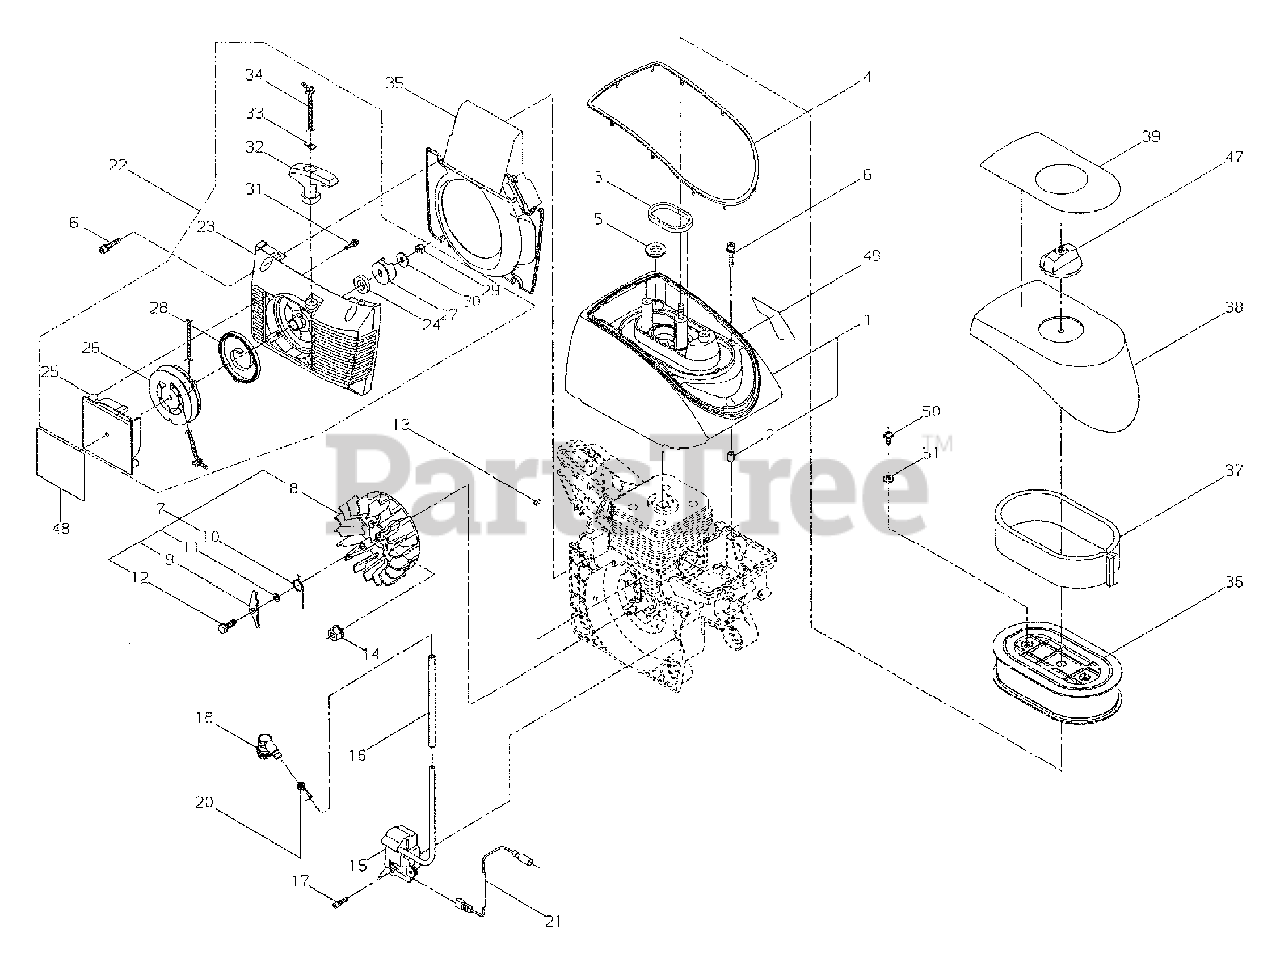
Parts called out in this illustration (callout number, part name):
1	ENGINE COVER KIT
3	SEAL
4	SEAT, SEAL
5	PLUG
6	BOLT 5
7	FLYWHEEL
8	FLYWHEEL
9	RATCHET
10	SPRING
11	COLLAR
12	BOLT
13	KEY, WOODRUFF 3×10
14	NUT M8×1.0
15	COIL
16	TUBE
17	BOLT M4×16
18	CAP, SPARK PLUG
20	TERMINAL, SPARK PLUG
22	STARTER ASSY
23	CASE, STARTER
24	SEAL, OIL
26	REEL
27	DOG
28	RECOIL SPRING
29	NUT, HEX M6
30	WASHER
32	GRIP, STARTER
33	RETAINER, ROPE
34	ROPE
35	DEFLECTOR, AIR
36	FILTER, AIR
37	PRE FILTER
38	COVER, AIR FILTER
39	LABEL - CAUTION
47	KNOB
48	LABEL - TRADE
49	LABEL - INSTRUCTION
50	SCREW
51	WASHER 5
